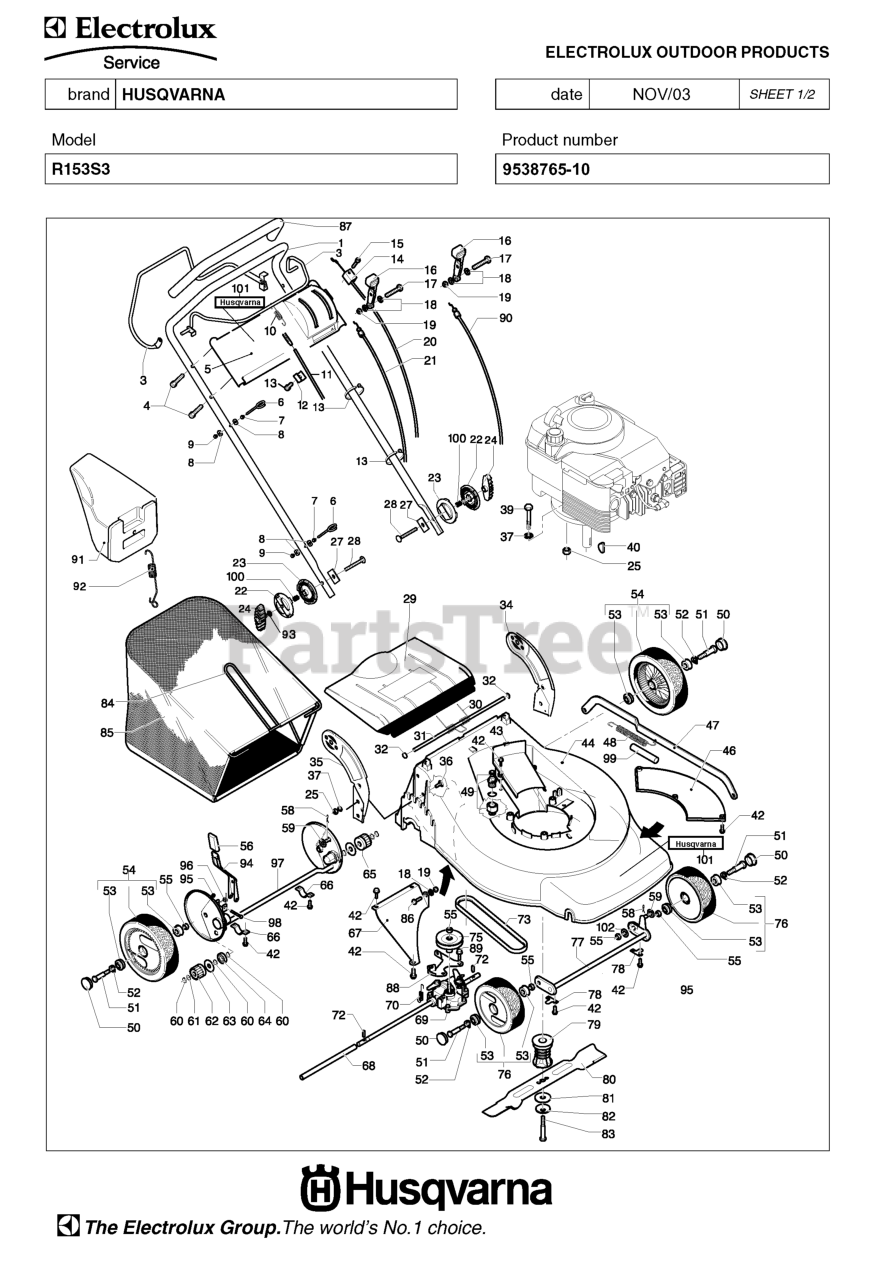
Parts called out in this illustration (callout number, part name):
42	Screws
58	Pins
60	Washers
